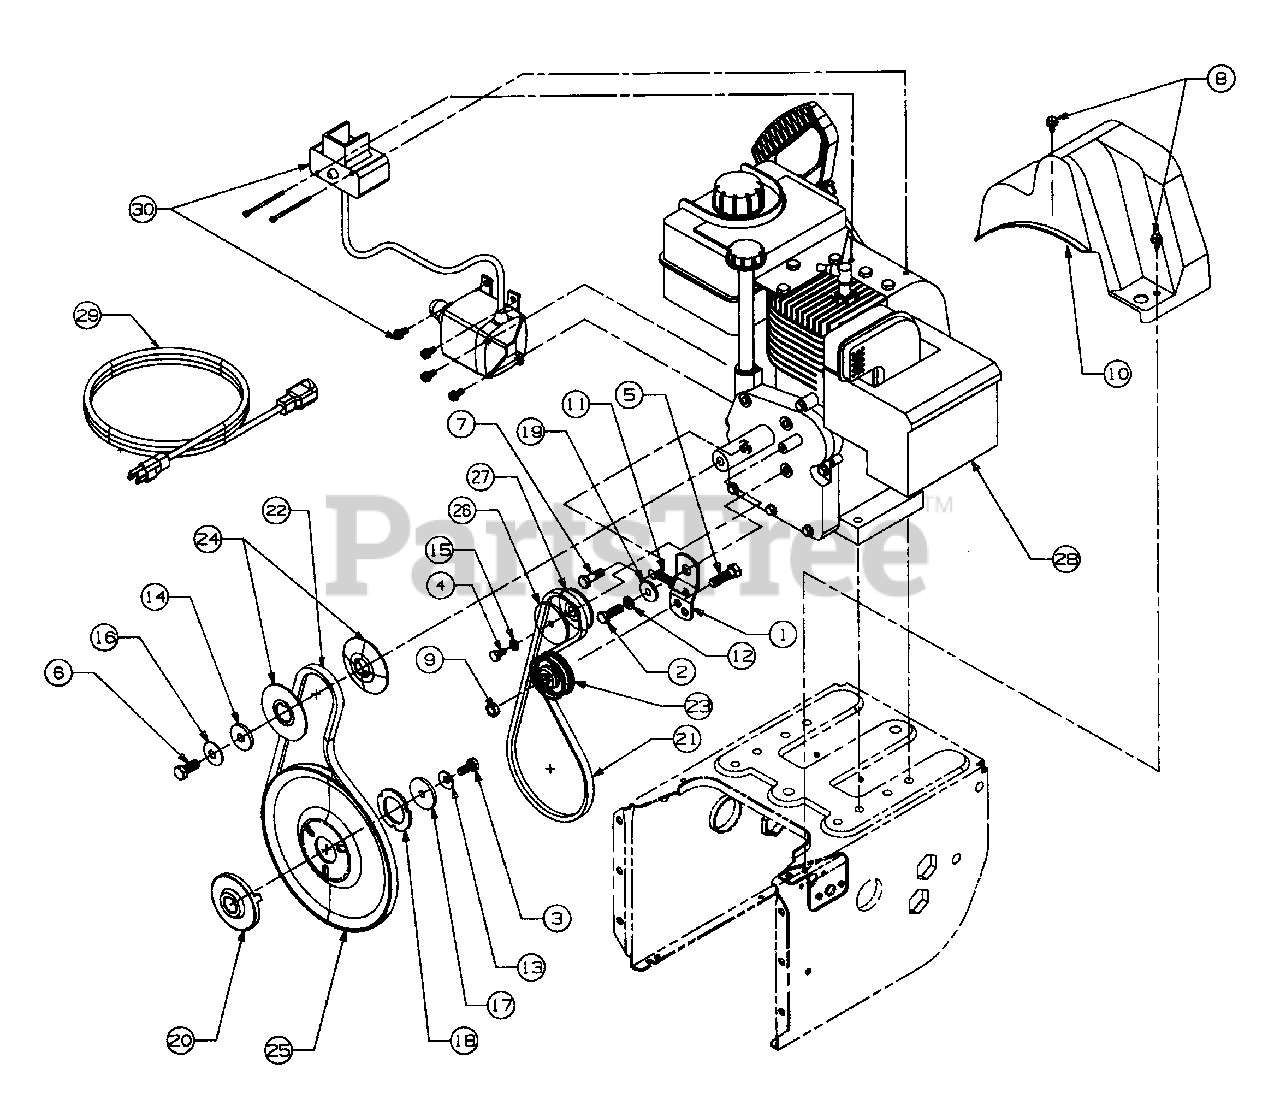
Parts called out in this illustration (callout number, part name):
3	Screw
4	Screw
5	Screw
6	Screw
7	Screw
8	Screw
9	Nut, Hex Jam
10	Belt Cover
11	Spring
12	Washer
13	Washer-Bell
14	Washer
15	Washer
16	Washer-Bell
17	Washer-Flat
18	Washer
19	Spacer
20	Pulley, Adapter
21	V-Belt
22	V-Belt Matched
23	Idler, Flat
24	Pulley, Half
25	Pulley, Auger
26	Pulley Half
27	Pulley, Half
28	Engine
29	Cord Extension
30	Starter
